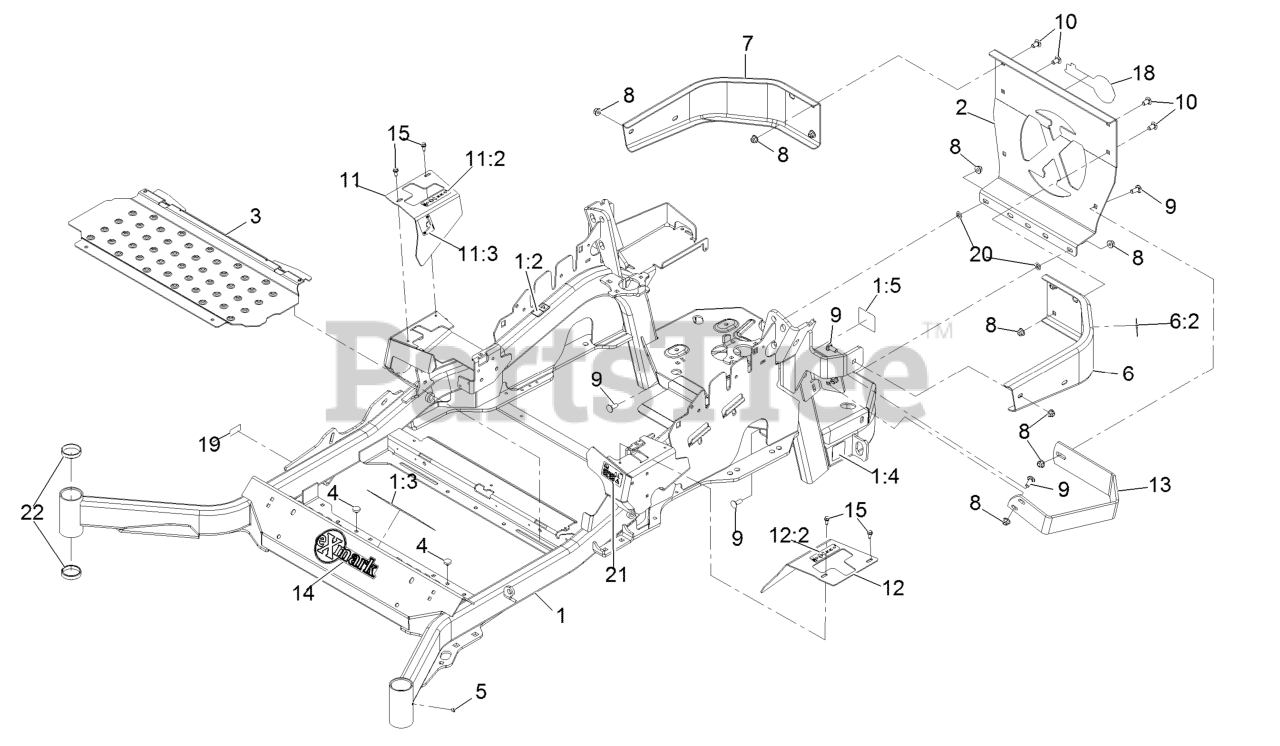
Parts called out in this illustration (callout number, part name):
1	MAINFRAME ASM
1:2	DECAL-WARNING
1:3	DECAL-DANGER
1:4	DECAL-HAZARD, PINCHED FINGER
1:5	DECAL-SPARK ARRESTER
2	PLATE,REAR GUARD
6	LH BUMPER ASM
6:2	DECAL-WARNING
7	BUMPER-RH
8	NUT-HF, NI
9	SCREW-CARR
10	SCREW-CARR
11	RH MOTION CONTROL COVER ASM
11:2	DECAL-CONTROL, MOTION
11:3	DECAL-PARK BRAKE, CE
12	LH MOTION CONTROL COVER ASM
12:2	DECAL-CONTROL, MOTION
13	GUARD-MUFFLER
14	DECAL-EXMARK LOGO
15	SCREW-HWH
18	DECAL-EXMARK LOGO
19	Decal-Patent
20	NUT-PUSH
21	DECAL-FUEL FILL, CE
22	CUP-BEARING
